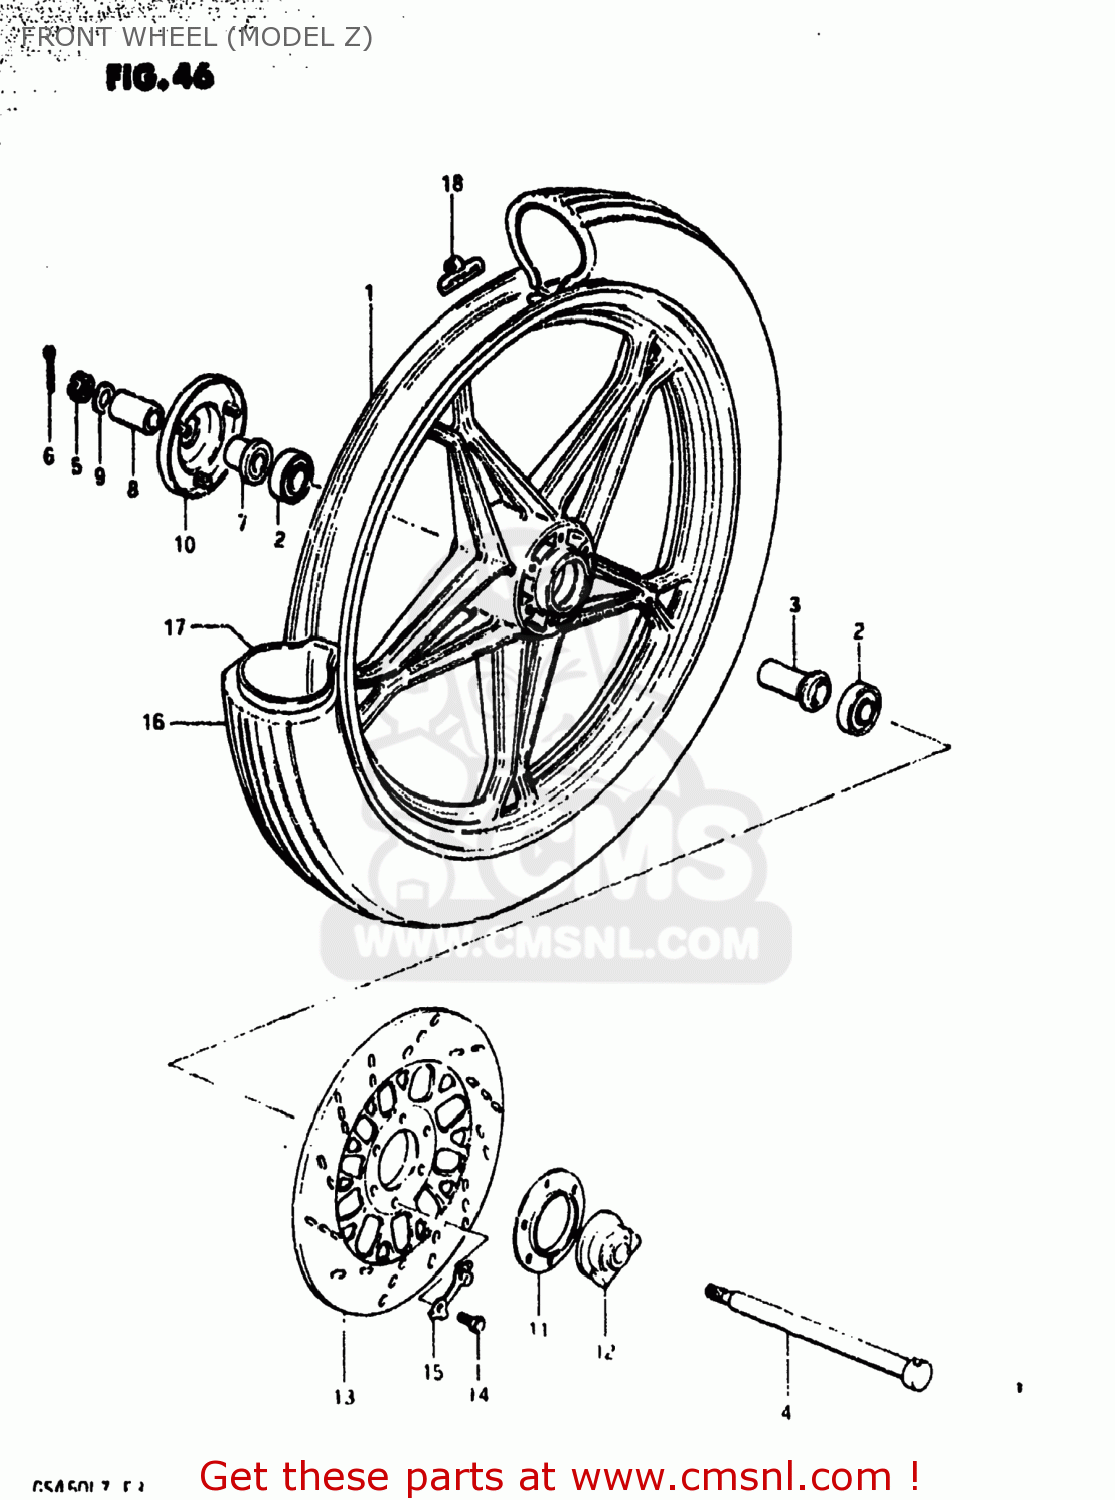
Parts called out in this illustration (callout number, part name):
1	CASTING WHEEL,FRONT 1.85
2	BEARING
3	SPACER,FR HUB BEARING
4	AXLE,FRONT
5	NUT 12MM
6	COTTER PIN
7	SPACER,FR HUB BEARING,R
8	SPACER(15X22X30)
9	WASHER
10	COVER,FR HUB,R
11	DUST SEAL,SPEEDOMETER GEAR BOX
12	BOX ASSEMBLY,SPEEDOMETER GEAR
13	DISC,FR BRAKE,L
14	BOLT(8X25)
15	WASHER
16	TIRE,FRONT
17	TUBE,INNER
18	BALANCER,WHEEL
